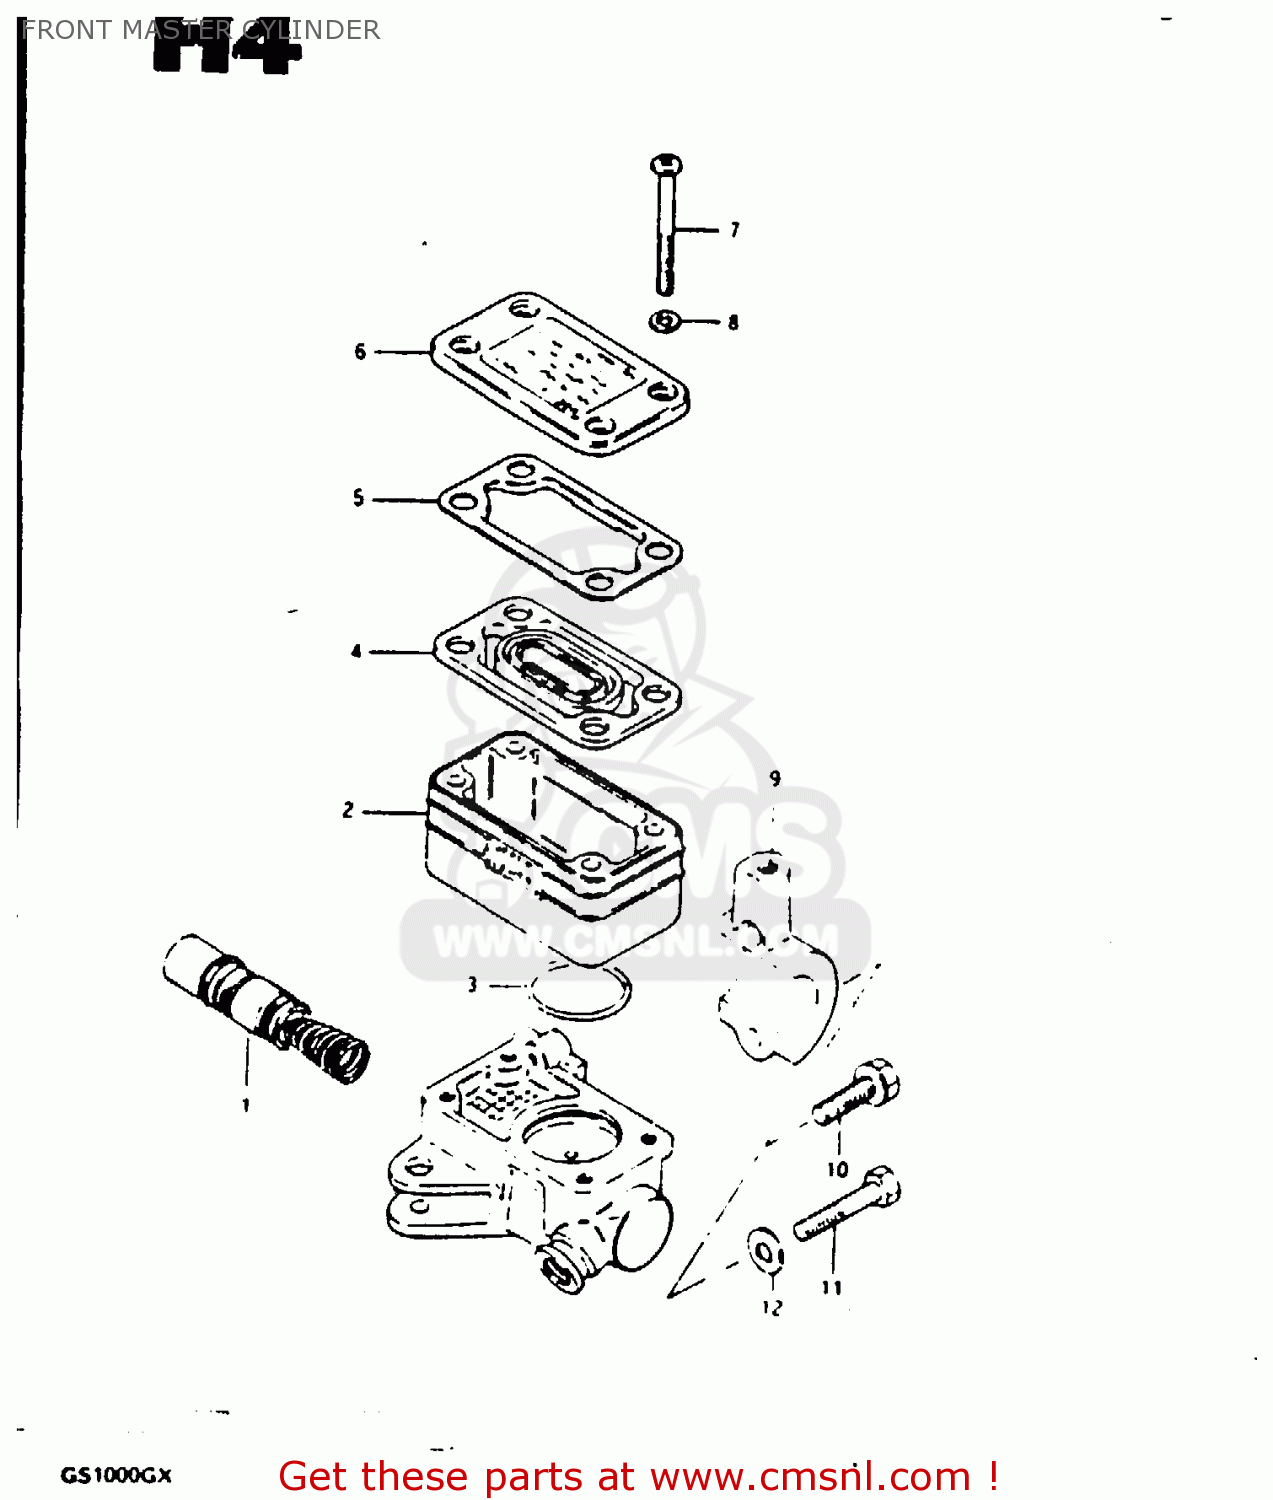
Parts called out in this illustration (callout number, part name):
1	PISTON & CUP SET
2	RESERVOIR
3	O RING
4	DIAPHRAGM
5	PLATE,DIAPHRAGM
6	CAP
7	SCREW
8	WASHER
9	HOLDER
10	BOLT,MASTER CYLINDER H
11	BOLT
12	WASHER
